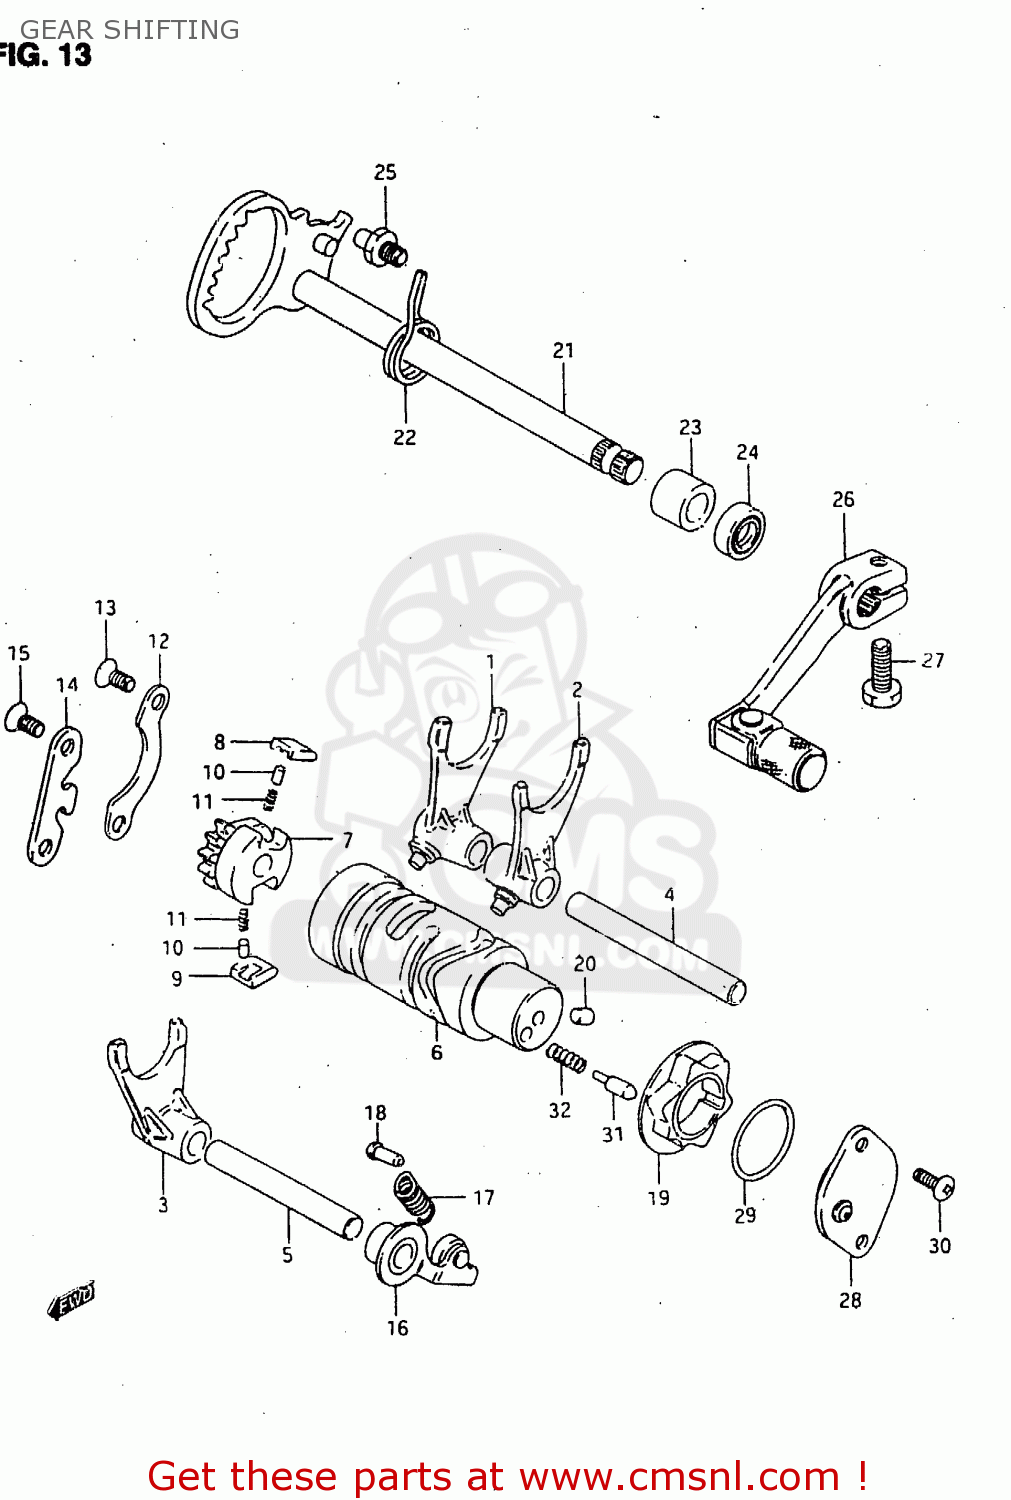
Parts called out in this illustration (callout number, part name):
1	FORK,GEAR SHIFT NO.1
2	FORK, GEAR SHIFT N-2
3	FORK,GEAR SHIFT NO.2
4	SHAFT,GEAR SHIFT FORK
5	SHAFT,GEAR SHIFT FORK
6	CAM,GEAR SHIFT
7	GEAR,GEARSHIFT CAM DRIVE
8	PAWL,GEAR SHIFT NO.1
9	PAWL,GEAR SHIFT NO.2
10	PIN(5X8)
11	SPRING
12	LIFTER,GEAR SHIFT POLE
13	SCREW
14	GUIDE,GEAR SHIFT CAM
15	SCREW
16	STOPPER,GEAR SHIFTING CAM
17	SPRING
18	RIVET
19	PLATE,GEAR SHIFT CAM STOPPER
20	PIN
21	SHAFT,GEAR SHIFT
22	SPRING
23	SPACER(12X20X15.3)
24	OIL SEAL
25	STOPPER,GEAR SHIFT CAM
26	LEVER ASSY,GEAR SHIFT
27	BOLT
28	BODY,GEAR SHIFT SWITCH
29	O-RING (D:2.4 ID:26.2)
30	SCREW
31	PIN(5X15.5)
32	SPRING
